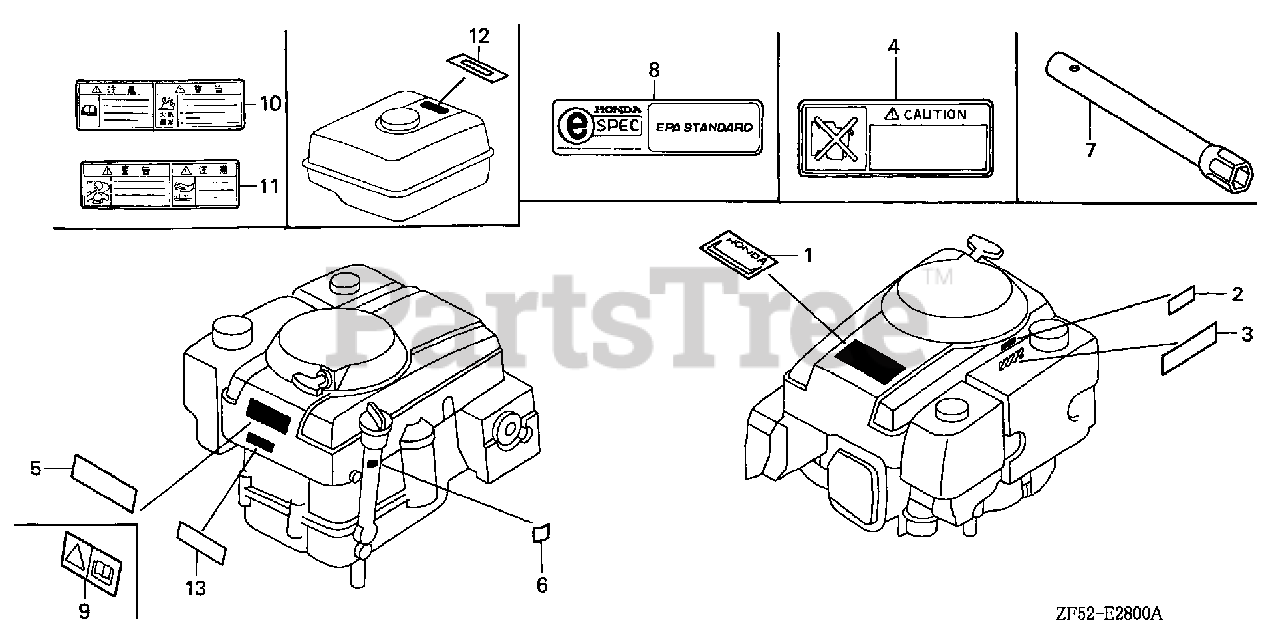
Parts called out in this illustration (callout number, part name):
1	EMBLEM, TOP COVER (13.0)
2	LABEL, FUEL CAUTION
3	LABEL, HONDA NAME
4	LABEL, MAINTENANCE CAUTION
5	LABEL, CAUTION
6	MARK, TYPE (DP23)
7	WRENCH, BOX (P21)
